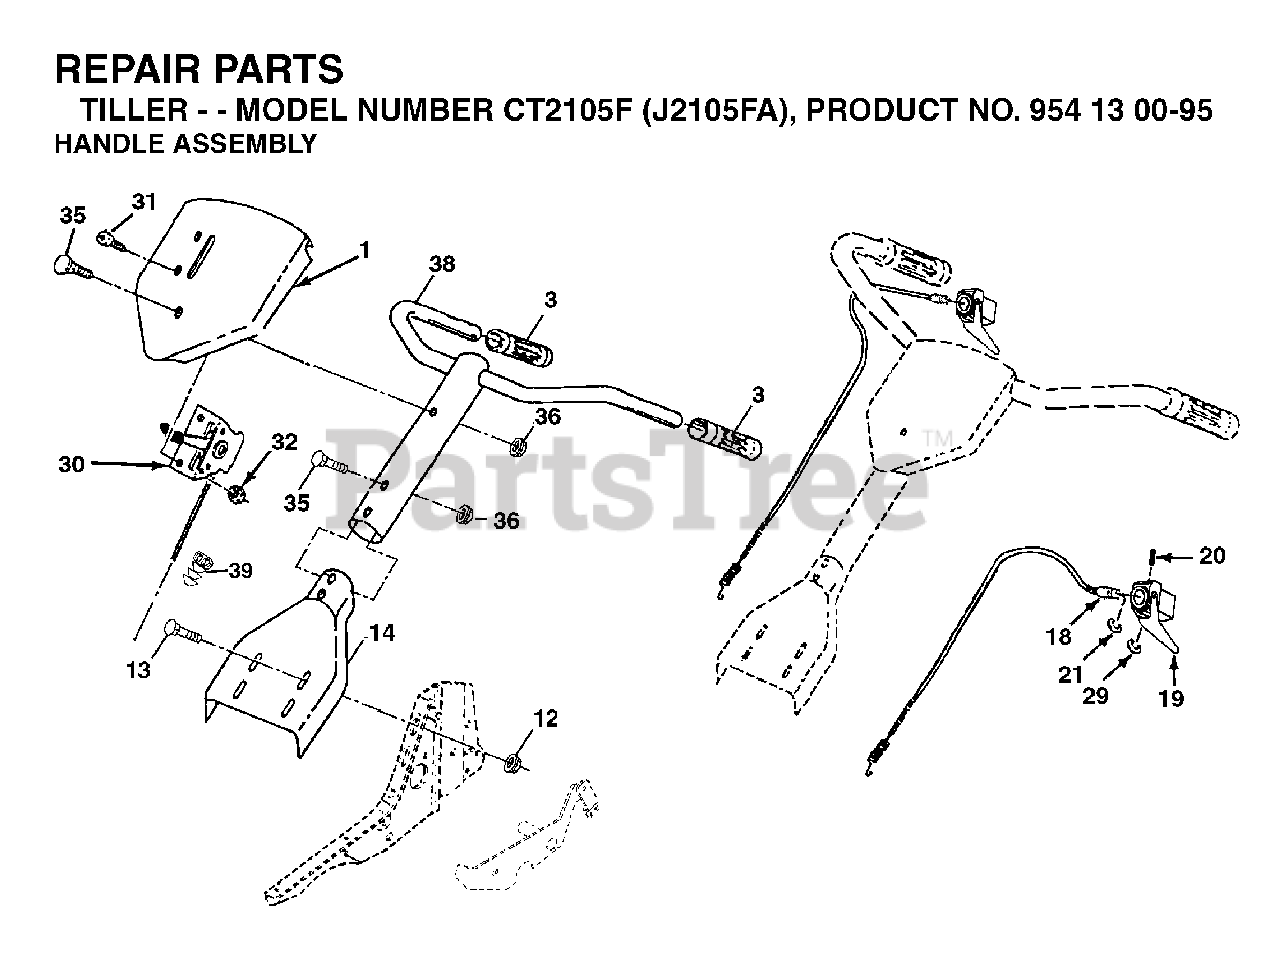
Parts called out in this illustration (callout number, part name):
12	NUT
13	BOLT.RH.SQNK.5/16
14	PANEL ASM. POLE
21	RETAINING RING
29	RETAINING RING
31	SCREW.PNHD.10-24
32	NUT **
35	BOLT.5/16-18X2.5
36	LOCKNUT-FLANGE 5/16-18
39	CLIP.ROUTING DUAL
